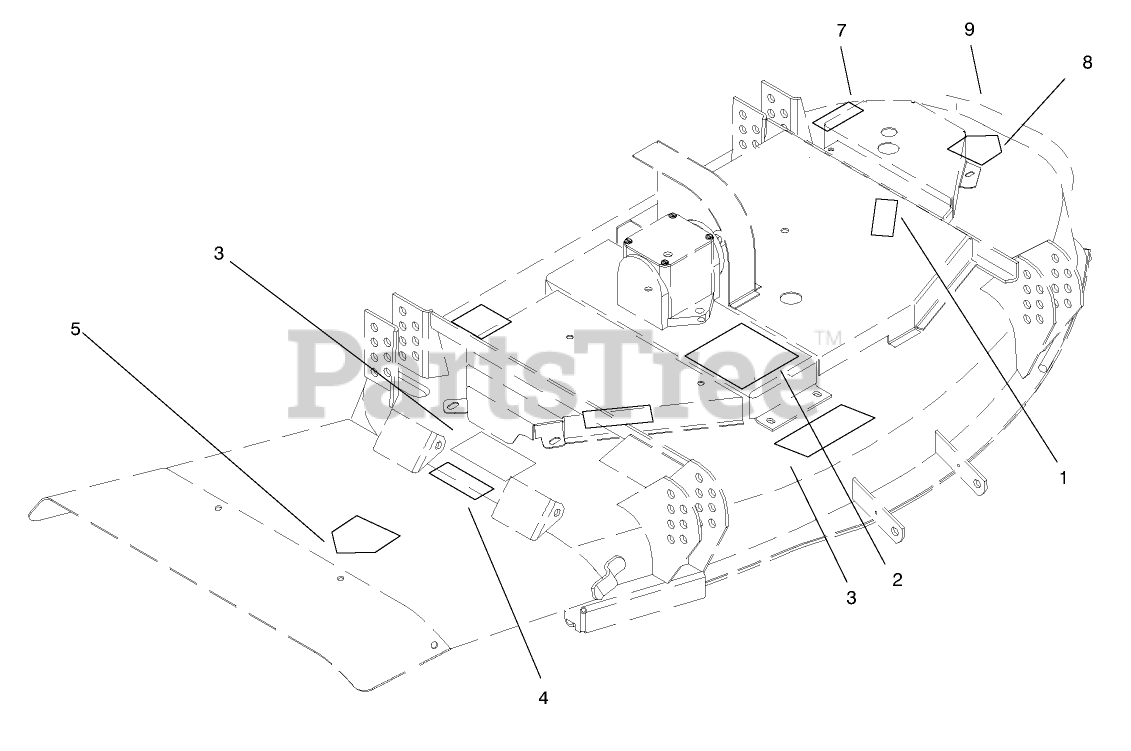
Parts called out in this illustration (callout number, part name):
1	DECAL-DANGER
2	DECAL-44 INCH
3	DECAL-DANGER, THROWN OBJECT
4	DECAL-DANGER
5	DECAL-DANGER
7	DECAL-TORQUE
8	DECAL-DANGER
9	DECAL-RECYCLER
